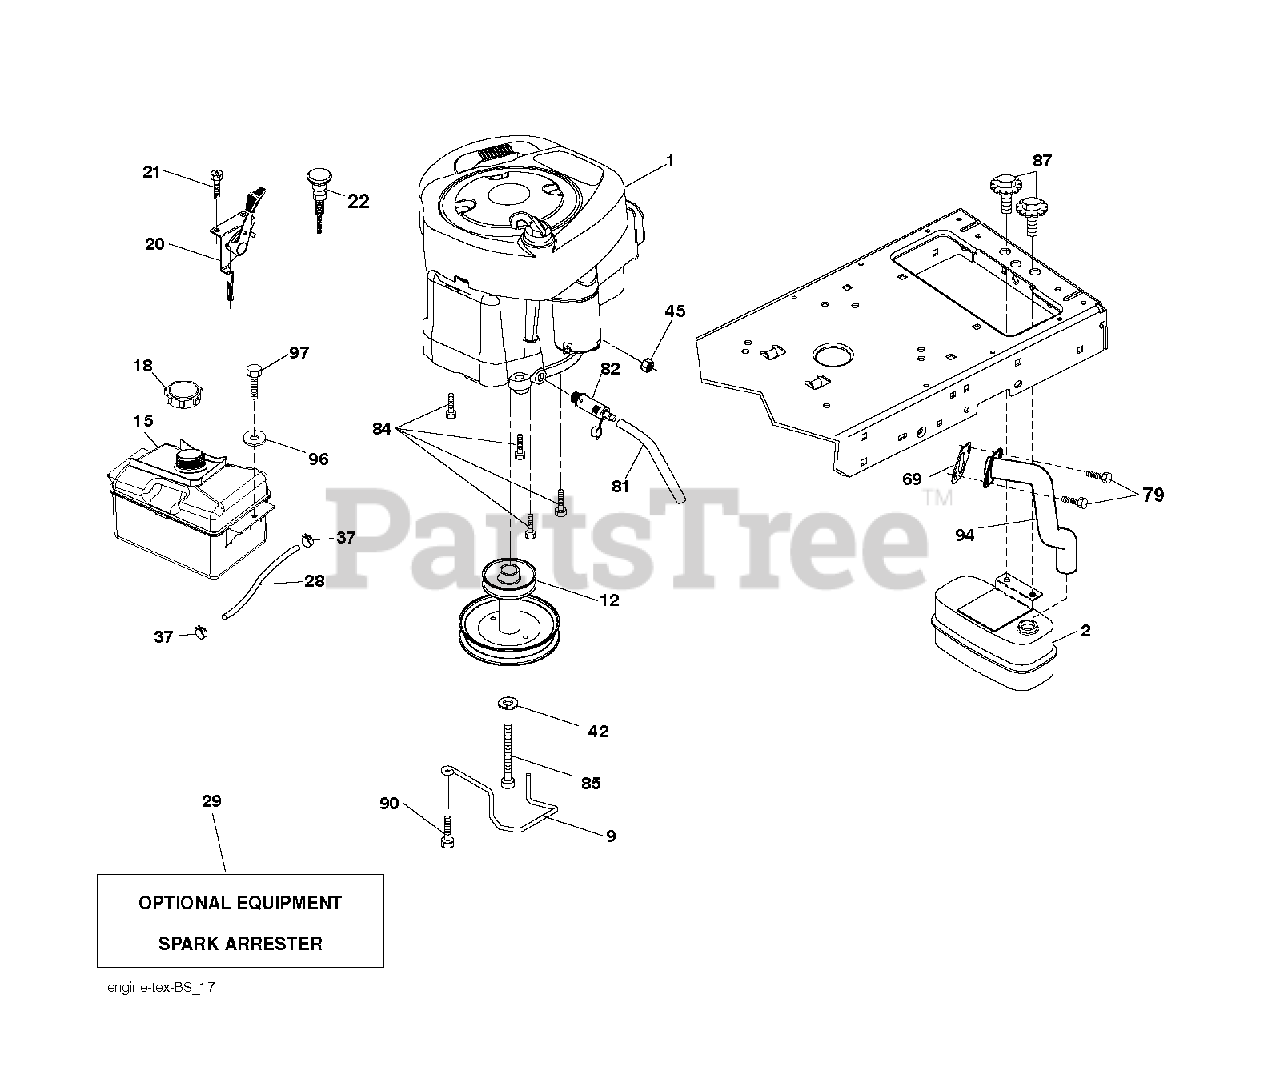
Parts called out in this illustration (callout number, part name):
2	MUFFLER.SINGLE.CYL.KOHL/B&S
9	KEEPER.BELT.ENGINE.3.25
12	PULLEY ENGINE
15	TANK FUEL FRT 1.5 GAL
18	FUEL CAP
20	CONTROL.TH/CK.C.
21	SCREW.#10 X 0.750.BOS THREAD
28	LINE.FUEL.20
29	ARRESTER SPARK (OPTIONAL)
37	HOSE CLAMP
42	LOCKWASHER
45	NUT
69	REPL BY 532 27 22-93
79	SCREW.SOCKET HD.5/16-1
81	TUBE, DRAIN OIL ASM.
82	PLUG DRAIN OIL EASY
84	SCREW.3/8-16
85	BOLT HEX 7/16-20X4-1/4"
87	BOLT, 5/16-18 X 1 3/4
90	SCREW 3/8-16X1
94	EXHAUST.TUBE.B&S.
97	SCREW HEXWSHR 1/4-20X3/4
